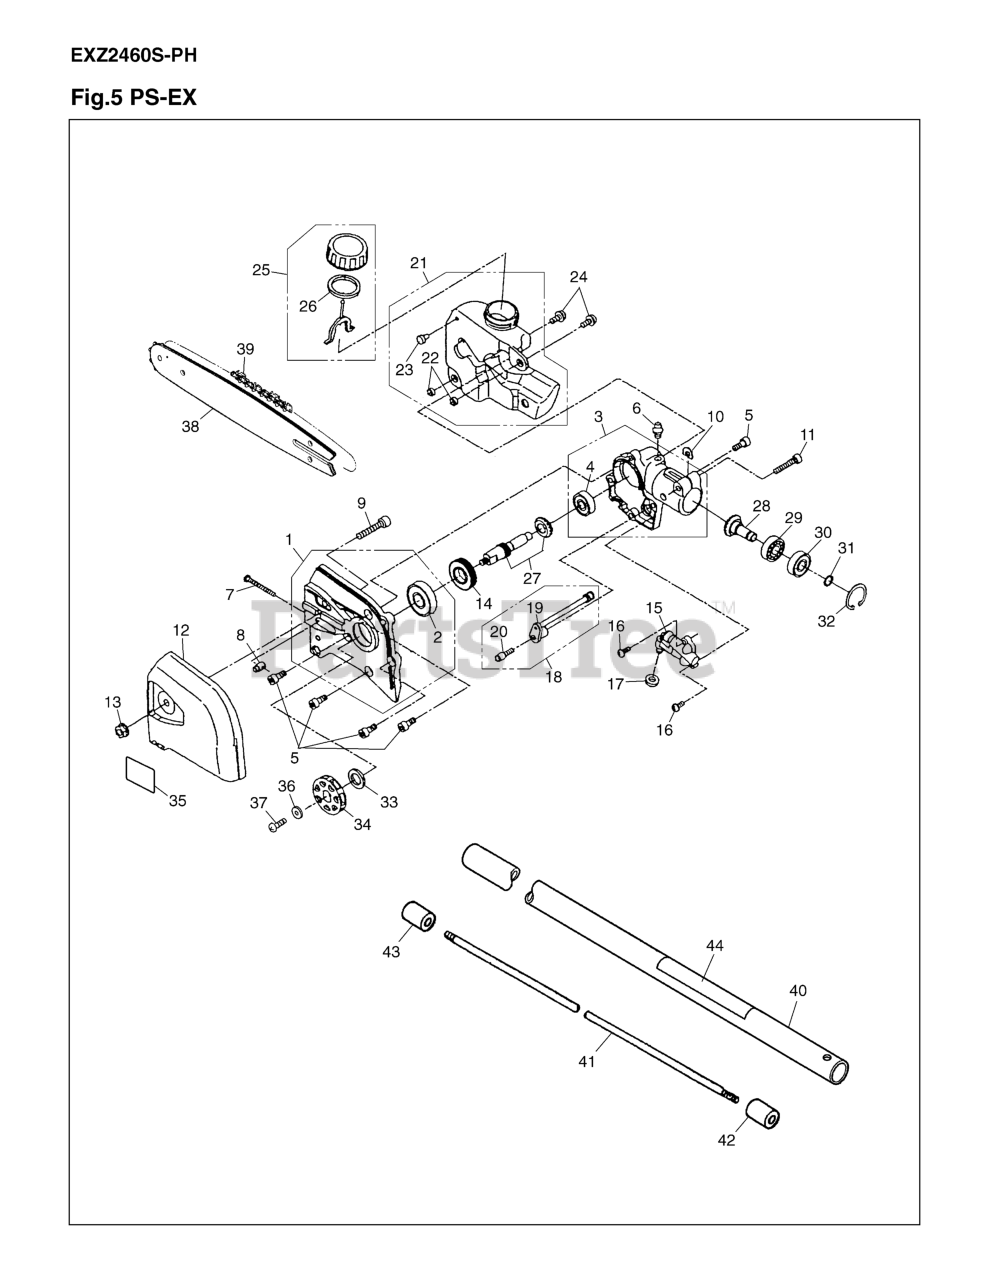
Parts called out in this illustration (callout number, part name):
1	GEAR CASE (L) COMP
3	GEARCASE COMP (R
5	BOLT, M5 x 12
6	FITTING, GREASE
9	BOLT, M6 x 30
11	BOLT
12	COVER, CHAIN
14	GEAR, WORM
15	PUMP ASSY, OIL
16	SCREW, M4 x 10
18	PIPE ASSY, OIL
19	PIPE, OIL
21	TANK ASSY,OIL(RP
24	SCREW, M5 x 12
25	CAP ASSY, OIL
26	GASKET, OIL CAP
27	SHAFT, GEAR
28	GEAR, BEVEL
29	BEARING (RPLS T3
31	RING, SNAP (RPLS
32	RING, SNAP, M24
34	SPROCKET
35	LABEL (PSZ2500)
38	BAR 12
39	CHAIN OREGON
40	PIPE COMPLETE
42	JOINT, SHAFT (RP
43	SPACER
44	NAMEPLATE
